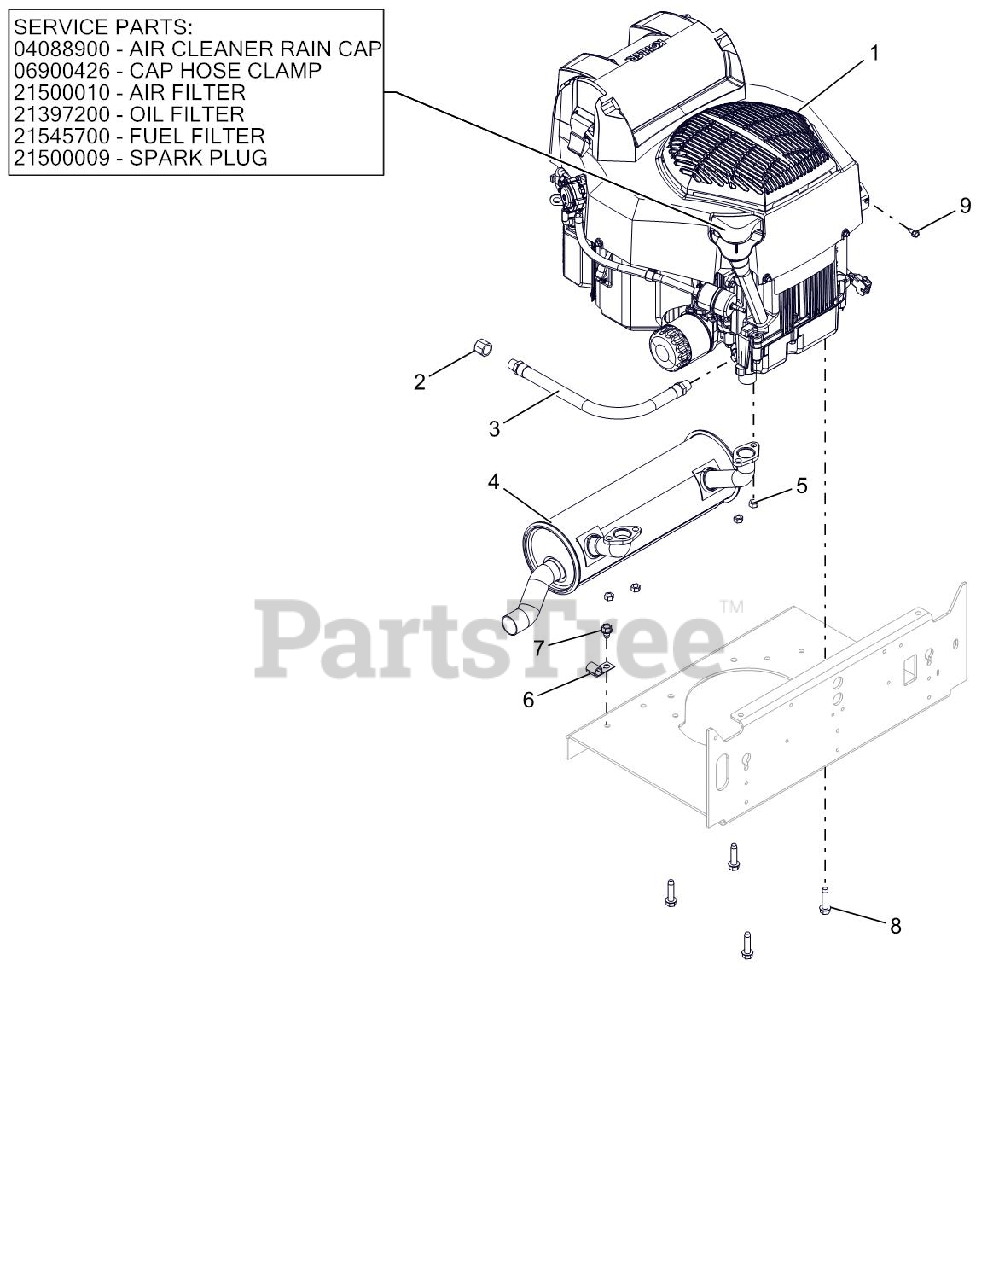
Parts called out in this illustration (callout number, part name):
1	AIR CLEANER RAIN CAP
1	CAP HOSE CLAMP
1	AIR FILTER
1	OIL FILTER
1	FUEL FILTER
1	SPARK PLUG
1	ENGINE, KOHLER
2	PIPE, CAP 3/8 NPT FEMALE
3	HOSE, HYD .38-11-OK M6N0-M6N0
4	MUFFLER, ZT730, ZT740
5	NUT-LK-TOP M8-1.25 YWZC
7	SCR-TAP .38-16X.50 HWH TR YWZ
8	SCR-TAP .38-16X1.50 HWH TR YZ
9	SCR-TAP .25-20X.50 HWH TR YWZ
